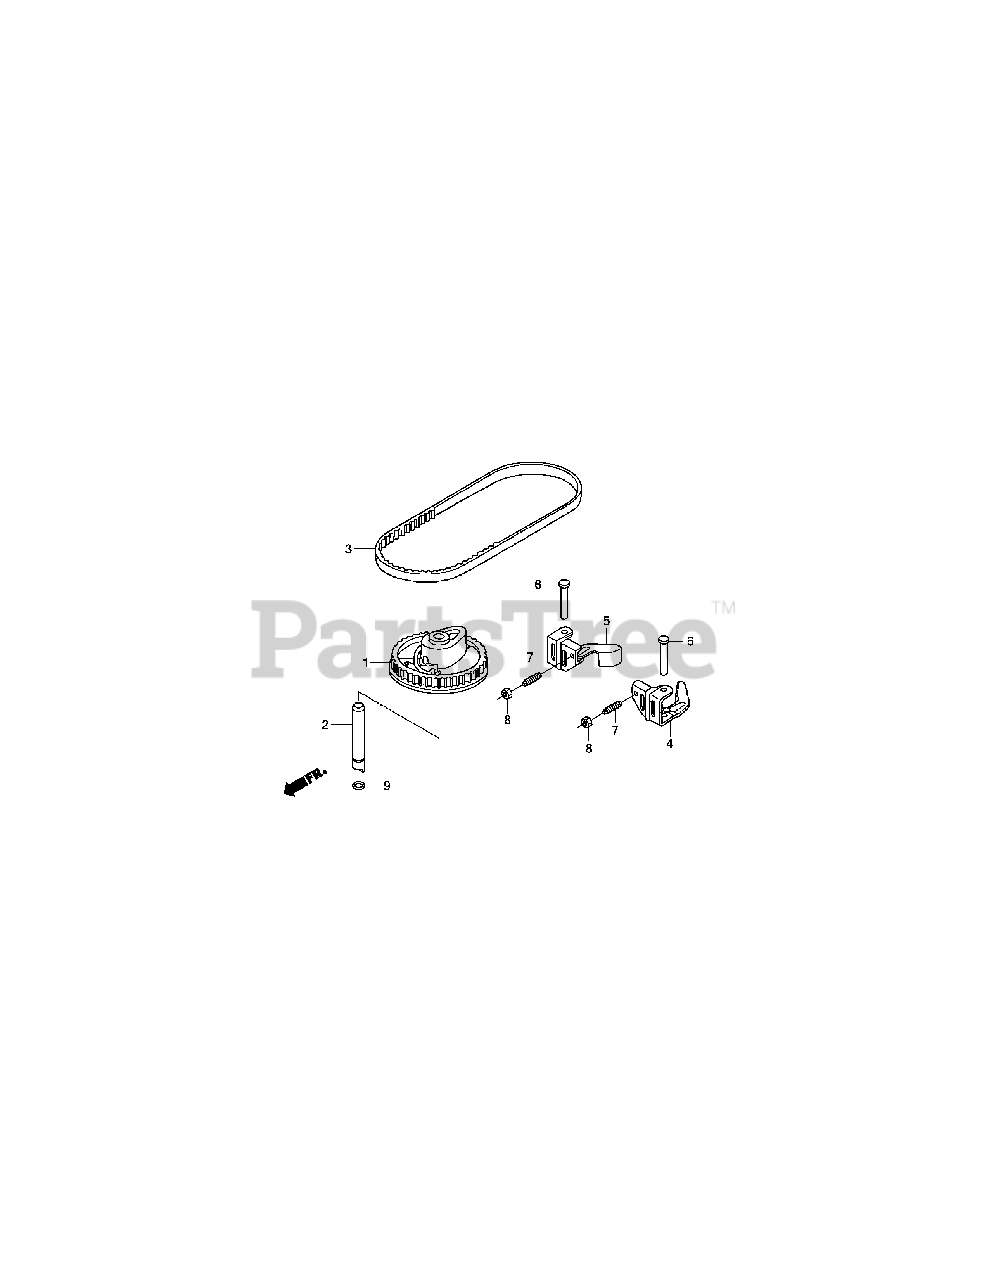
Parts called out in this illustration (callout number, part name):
1	Camshaft Pulley
2	Cam Pulley Shaft
3	Timing Belt
4	Intake Rocker Arm
5	Exhaust Rocker Arm
6	Rocker Arm Shaft
7	Tappet Adjusting Screw
8	Tappet Adjusting Nut
9	O-Ring,6.8x1.9
